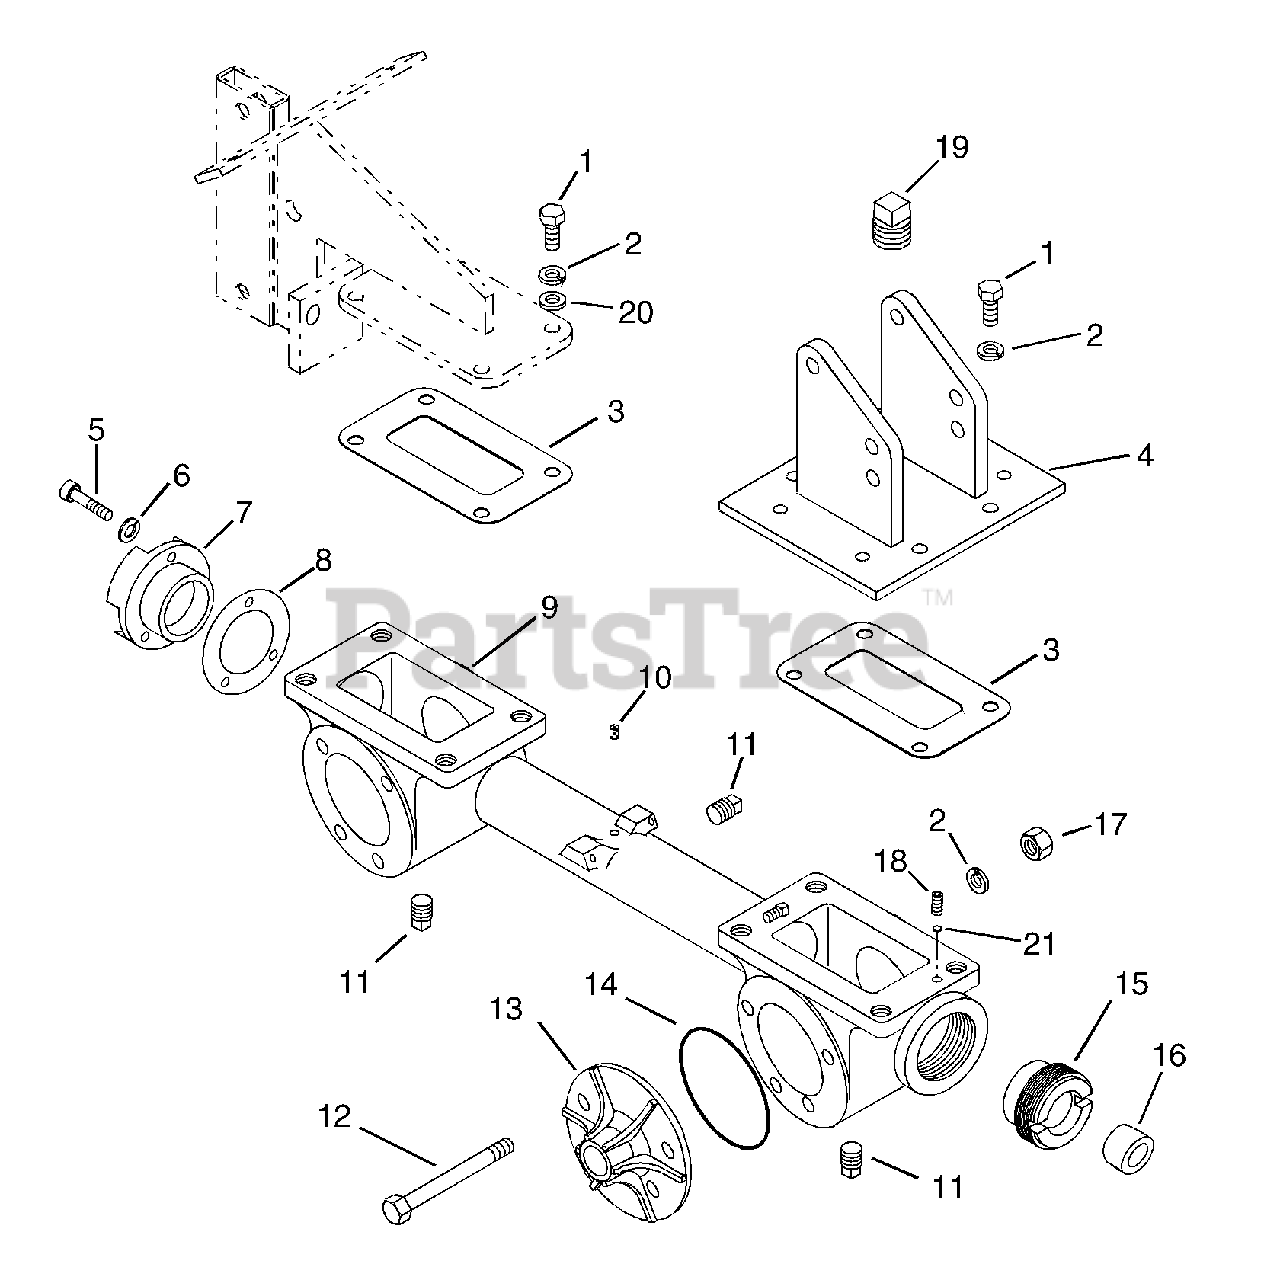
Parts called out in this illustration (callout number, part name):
1	@BLT-HEX .31-18X1.00 GR5 YWZC
2	@WSHR-LK .31X.078 REG YWZC
4	HANDLEBAR MOUNT
5	SCR-CAP.25-20X.75 SKT HD
6	@WSHR-LK .25X.062 REG YWZC
7	REAR CAP
8	GASKET - REAR CAP
9	GEAR CASE
10	BREATHER
11	PIPE PLUG, 1/4 NPT
12	@BLT-HEX .31-18X3.50 GR5 YWZC
13	AXLE HOUSING
14	O-RING 3.625X3.875X.135
15	ADJUSTMENT PLUG
16	SEAL .750X1.250X.136
17	@NUT-HEX .31-18 YWZC
18	SCR-SET .25-20X.25 SKHCUPDL
19	PIPE PLUG
20	@WSHR-FL-STL.344X.688X.065YWZC
